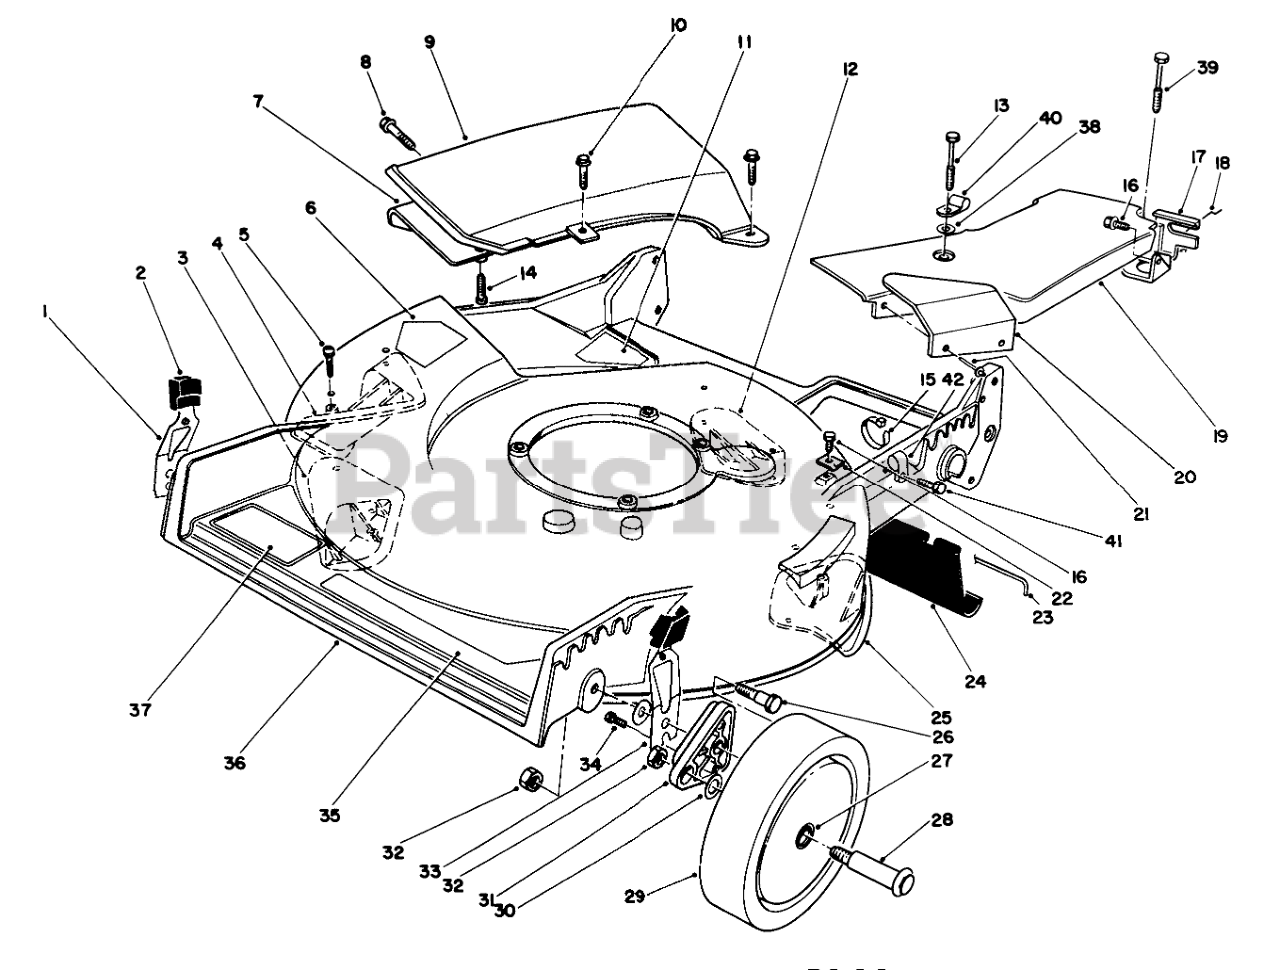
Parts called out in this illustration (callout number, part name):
1	RH SPRING ARM ASSEMBLY
2	KNOB-ARM
3	KICKER
4	KICKER
5	SCREW-PPH
6	DECAL-DANGER
7	Deflector-Recycler
8	SCREW AND WASHER ASM
9	Cover Assembly (Incl. Ref. #7 & 14)
10	SCREW-HWH
11	DECAL - DANGER
12	KICKER
13	SCREW-SPECIAL
15	TIE-CABLE
16	SCREW-HWHTF
17	Bracket-Adj. Trac
18	RETAINER-CABLE
19	Belt Cover Assembly (Incl. Ref. #20 & 21)
20	HEAT SHIELD
21	RIVET-HEAD, FLAT
22	CLAMP-CABLE
23	ROD-SHIELD
24	SHIELD-TRAILING
25	KICKER
26	SCREW-SHOULDER
27	BUSHING
28	WHEEL BOLT
29	Wheel & Tire Assembly (Incl. Ref. #27)
30	WASHER
31	ARM-PIVOT, FRONT
32	Nut
33	LH SPRING ARM ASSEMBLY
34	SCREW-HWH
35	DECAL - DECK
36	Housing Assembly (Incl. Ref. #3-6, 12, & 25)
37	DECAL
38	WASHER
39	SCREW-HHFTF
40	CLAMP-CABLE
41	SCREW
42	CLAMP-CABLE
